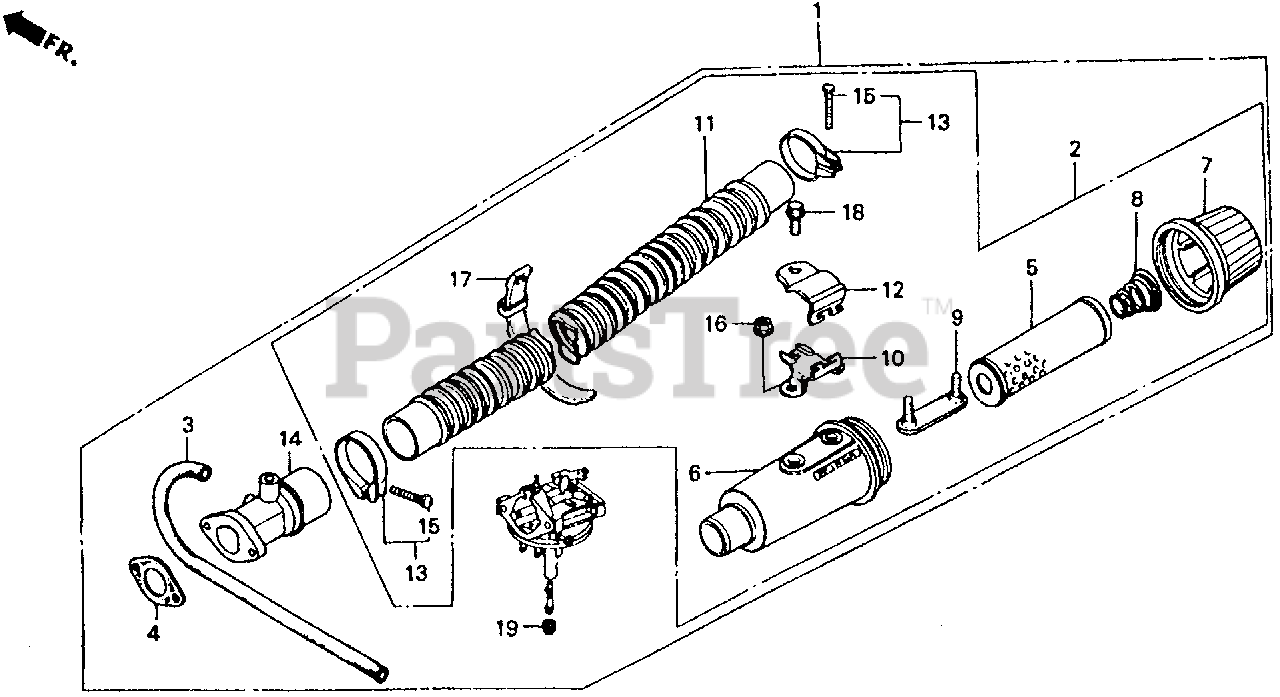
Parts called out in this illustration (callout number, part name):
1	AIR CLEANER KIT, SNORKEL (NOT AVAILABLE)
2	AIR CLEANER KIT, SNORKEL
3	TUBE, BREATHER
4	GASKET, AIR CLEANER
5	ELEMENT, AIR CLEANER
6	HOUSING, AIR CLEANER
7	CAP, AIR CLEANER
8	SPRING, SETTING
9	PLATE, AIR CLEANER SETTING
10	BRACKET A, AIR CLEANER
11	HOSE, AIR CLEANER
12	BRACKET B, AIR CLEANER
13	BAND, AIR CLEANER CONNECTING TUBE
13	BAND, AIR CLEANER CONNECTING TUBE (34)
14	JOINT, TUBE CONNECTING
15	SCREW, PAN (4X25)
16	NUT, FLANGE (6MM)
17	BAND B3, CABLE HARNESS
18	BOLT, FLANGE (6X16)
19	JET, MAIN (#65)
